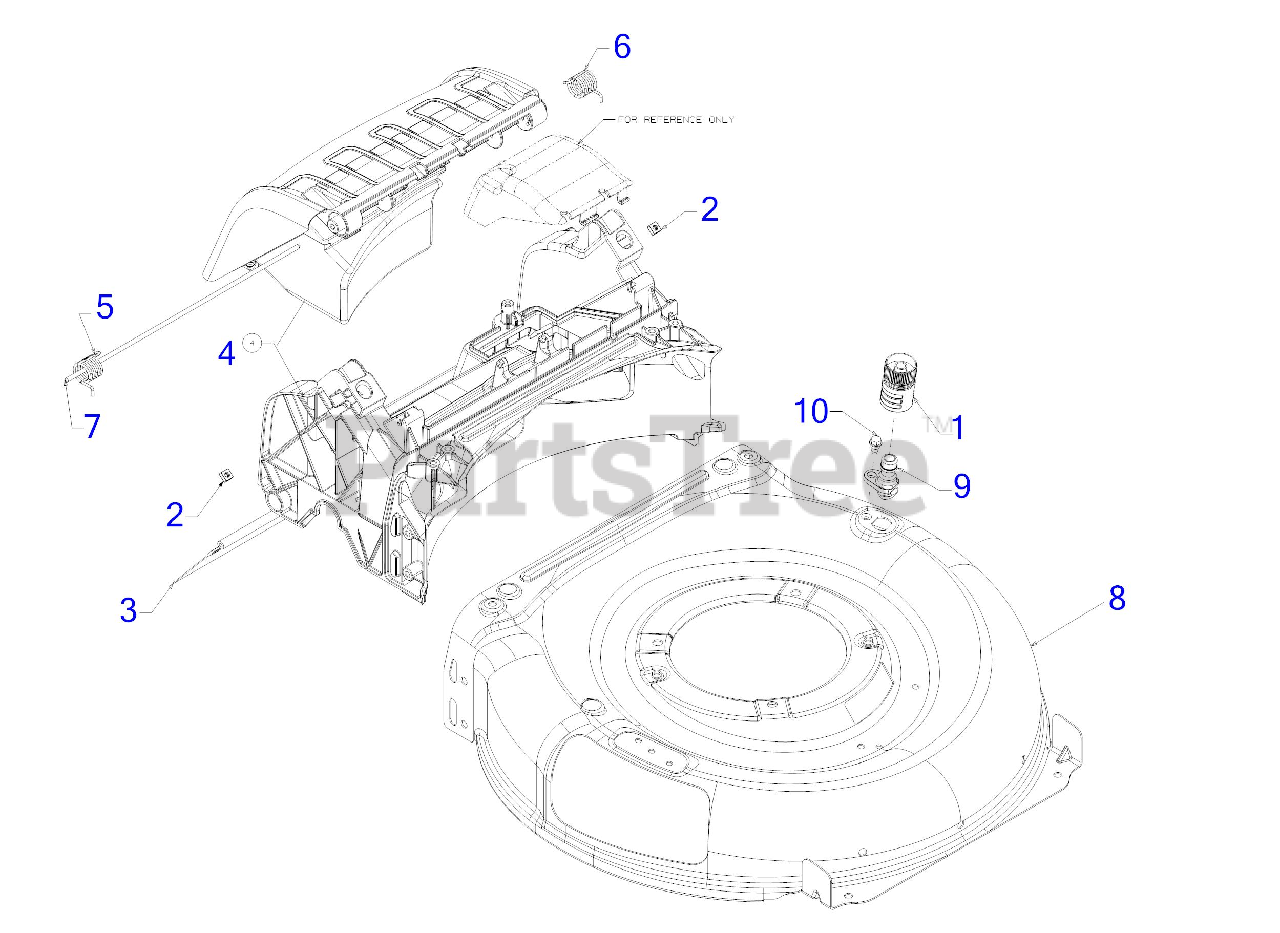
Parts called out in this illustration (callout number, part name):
1	WATER NOZZLE
2	SQUARE NUT 1/4-20
3	TRAILSHIELD
4	REAR BAG BAFFLE ASSEMBLY
5	TORSION SPRING (RH)
6	TORSION SPRING (LH)
7	REAR DOOR PIVOT ROD
8	21" DECK (3N1)
9	DECK WASH NOZZLE
10	SHOULDER SCREW 1/4-20 x .50
